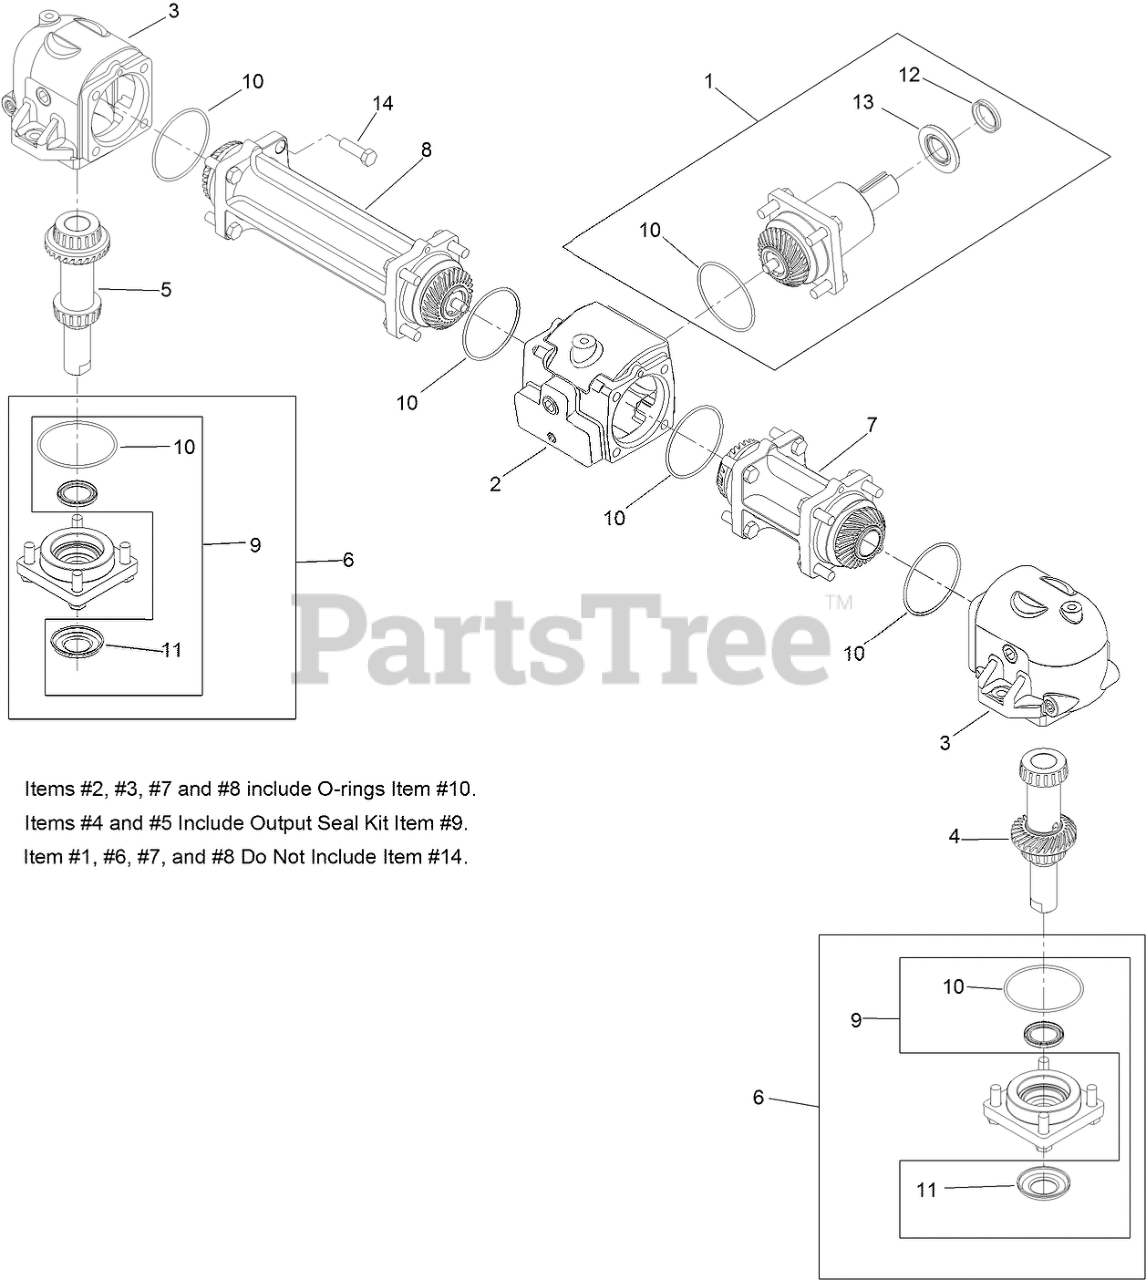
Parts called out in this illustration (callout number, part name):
1	INPUT PINION ASM
2	HOUSING-CENTER
3	HOUSING-END
4	LH OUTPUT SHAFT AND GEAR
5	RH OUTPUT SHAFT AND GEAR
6	CAP-OUTPUT
7	TUBE-CONNECTOR, SHORT
8	TUBE-CONNECTOR, LONG
9	OUTPUT SEAL KIT
10	SEAL-O-RING
11	WASHER-CUPPED
12	SEAL-V-RING
13	SEAL-INPUT
